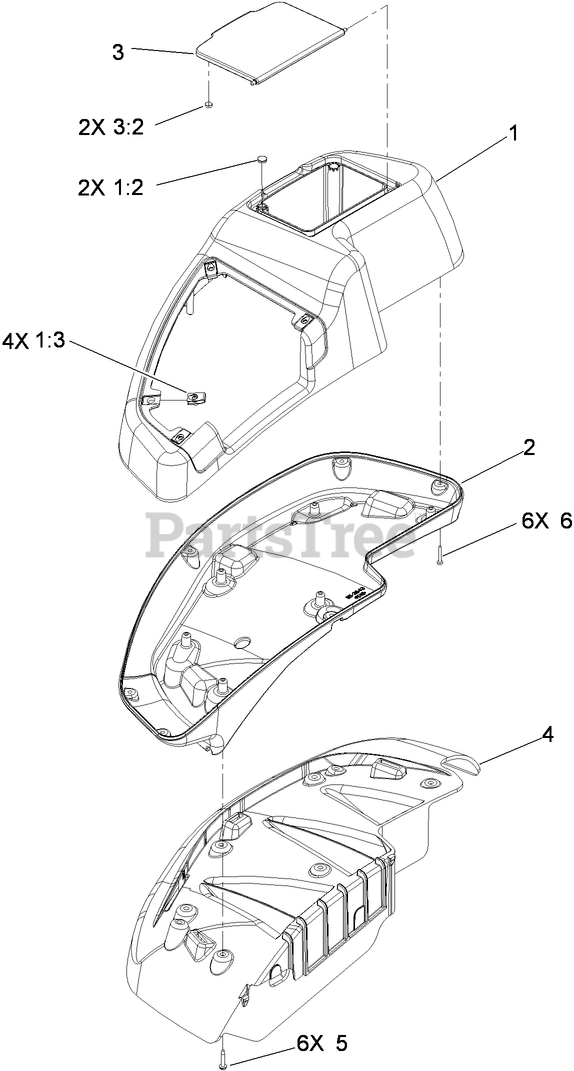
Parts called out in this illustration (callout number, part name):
1	RH WIDE TOP CONSOLE ASM
2	CONSOLE-LOWER, RH WIDE
3	WIDE LID ASM
3:2	MAGNET
4	FENDER-WIDE, RH
5	SCREW-THREAD FORMING
6	SCREW-PPH
